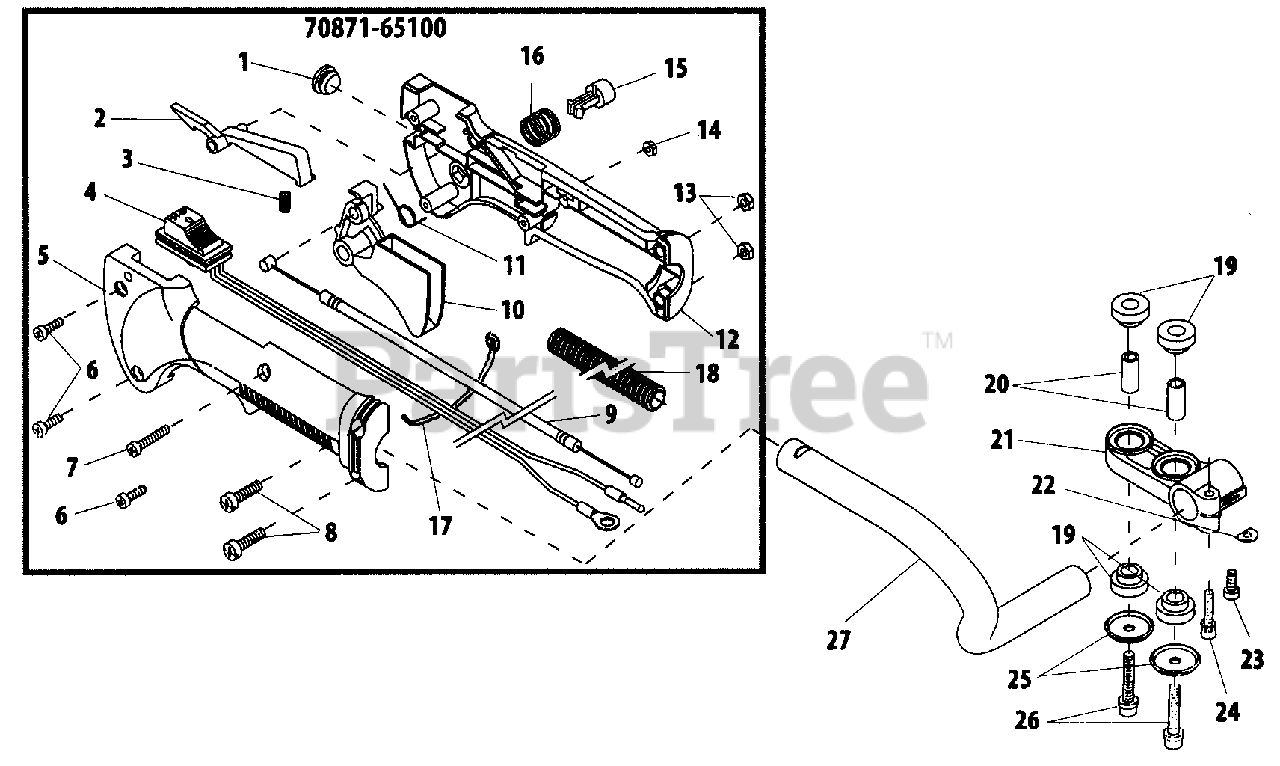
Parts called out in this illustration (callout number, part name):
1	PLUG
2	LEVER, TRIGGER LOCKOUT
3	SPRING
4	SWITCH ASSY
5	HANDLE, CONTROL - LEFT
6	SCREW - 4X16 -- TAPPING
7	SCREW - 4X23
8	SCREW - 5X20
9	CABLE, THROTTLE
10	TRIGGER, THROTTLE
11	SPRING
12	HANDLE, CONTROL - RIGHT
13	NUT - 5
14	NUT - 4
15	BUTTON, THROTTLE LOCK
16	SPRING
17	TIE, CABLE
18	TUBE, PROTECTIVE - CORRUGATED
19	CUSHION
20	COLLAR - 6
21	STAY, HANDLE
22	SHIM
23	SCREW - 5X12
24	SCREW - 5X25
25	COVER, CUSHION
26	SCREW - 6X35
27	HANDLE - REAR
70871-65100	THROTTLE LEVER ASSY
